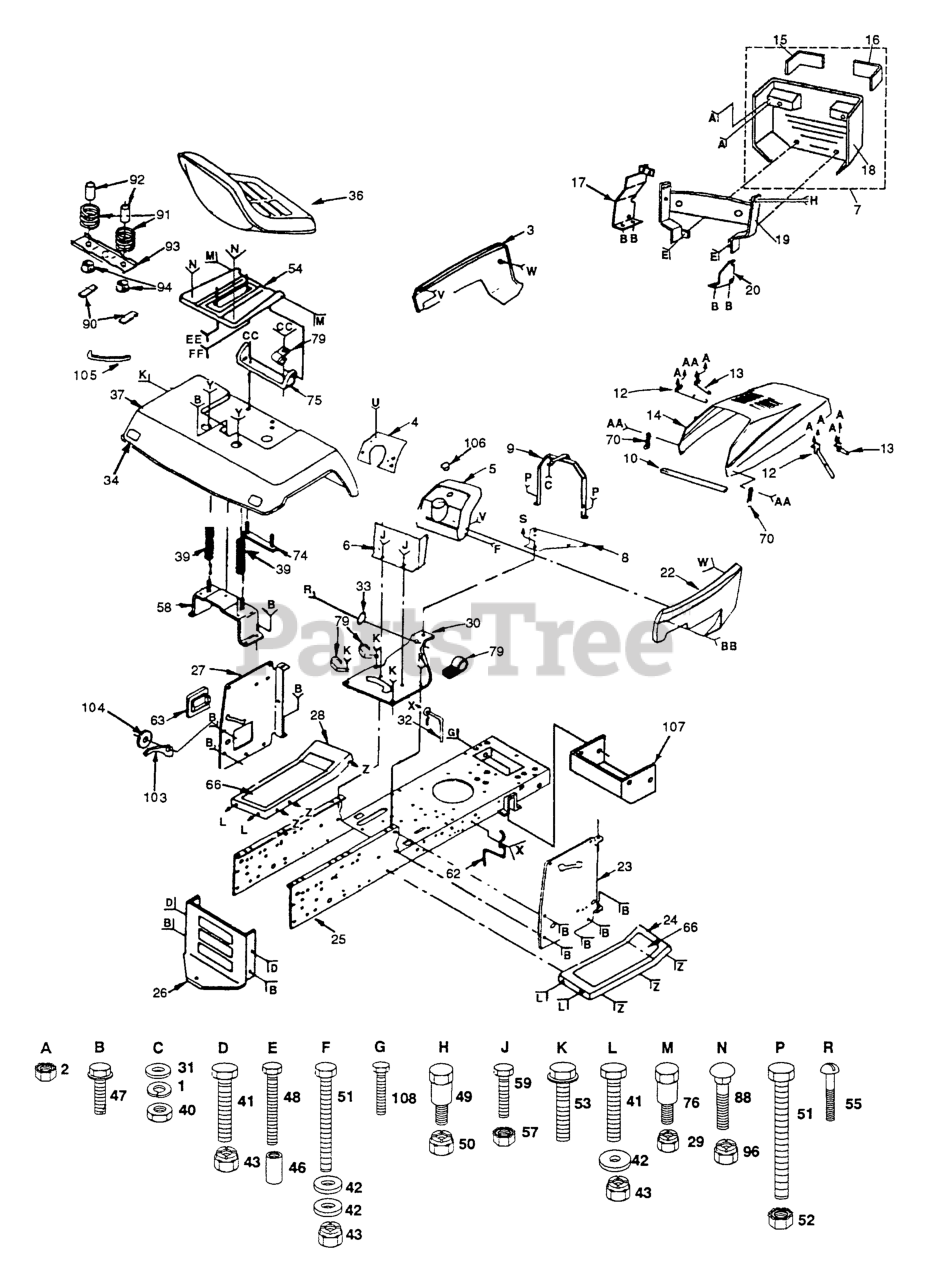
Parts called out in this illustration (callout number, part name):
1	LOCKWASHER
2	NUT
3	PANEL,SIDE LH
4	DASH PLATE NLA
5	DASHBOARD
6	DASH ASSY LT NLA
7	GRILL
8	PLATE SUPPORT T NLA
9	SUPPORT ASS'Y
10	FOAM-STRIP LT
12	STRAP ASSY LT
13	STRAP ASSY LT
14	HOOD
15	LENS LH
16	LENS RH
18	GRILL
19	SUPT, ASS'Y GRILL
20	SUPPORT LH YTH
22	PANEL,SIDE RH
23	PANEL-DASH (L)
24	PAD,SPACER
27	Panel, Dash, L.H.
28	ROLL PIN NLA
29	LOCKNUT
30	SADDLE
31	WASHER PM
32	BELT GUIDE
33	BUSHING LT
34	REFLECTOR-TAIL YT
36	SEAT
39	SPRING COMPRESSION
40	NUT
42	WASHER
47	SCREW
49	BOLT T
50	NUT.CROWNLOCK.1/4
53	SCREW LT
55	SCREW LT
57	NUT
58	BRACKET-FENDER YT
59	Screw, Truss Hd. 5/16-18 x 3/4
62	BELT GUIDE
63	COVER ACCESS
66	PAD FOOTREST T
70	LATCH.HOOD.
74	STRAP-FENDER YT
75	BRKT,SEAT PIVOT
76	BOLT, SHOULDER LT
79	CLIP T
88	Bolt Carriage 1/4 - 20 x 1-1/4
90	STRIP FORM
92	SPACER SPLIT
93	BRKT SWITCH
96	NUT T
103	POINTER HGT INDAT
105	REPL BY 532 06 64-26
106	PLUG BUTTON T
107	HEAT SHIELD
